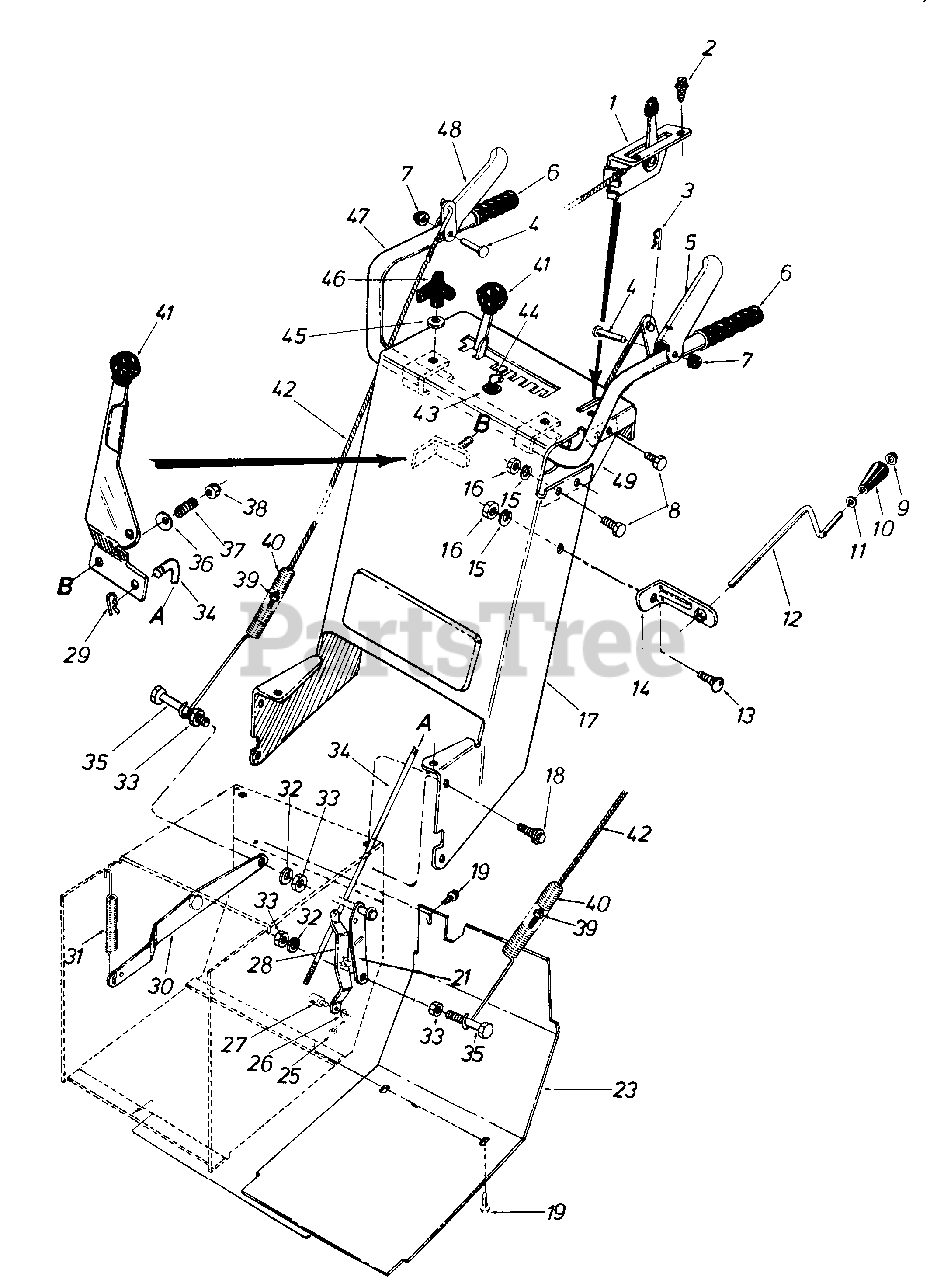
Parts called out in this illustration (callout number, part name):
1	Throttle Control Ass'y. Comp.
2	Hex Wash. Hd. AB-Tap Scr. #8 x .50
3	Hairpin Cotter 3/32" Dia. x 1.00" Lg.
4	Clevis Pin .375" Dia. x 1.88" Lg.
5	Drive Clutch Grip Ass'y. - L.H.
6	Grip Handle
7	Push Cap for 3/8" Rod
8	Hex Bolt 5/16-24 x .62" Lg.
9	Push Nut for 3/8" Rod
10	Knob w/.38" Dia. Hole
11	Fl. Wash. .385" I.D. x .62" O.D. x .063"
12	Chute Crank .38 Dia. x 35" Lg.
13	Carriage Bolt 5/16-18 x .62" Lg.
14	Chute Control Brkt.
15	L-Wash. 5/16"
16	Hex Nut 5/16-24 Thd.
17	Handle Panel Ass'y.
18	Hex Wash. Self-Tap Scr. 5/16-24 x .50" Lg.
19	Hex Wash. Self-Tap Scr. 5/16-24 x .50 Lg.
21	Drive Clutch Brkt. Ass'y.
23	Frame Cover
25	Cotter Pin 3/32" Dia. x .75" Lg.
26	Fl. Wash. .344" I.D. x .62" O.D. x .063
27	Ferrule - Engagement
28	Shifting Linkage Brkt.
29	Hairpin Cotter 3/32" Dia. x 1.00" Lg.
30	Auger Clutch Brkt.
31	Ext. Spring .38" O.D. x 3.18" Lg.
32	L-Wash. 1/4" I.D.
33	Hex Nut 1/4-28 Thd.
34	Shifting Rod
35	Hex Bolt 1/4-28 x 1.75" Lg.
36	Bell-Wash. .400 I.D. x .88 O.D. x .060
37	Comp. Spring .39 I.D. x .88
38	Hex Ins. L-Nut 3/8-24 Thd.
39	Hex Ins. L-Nut 1/4-20 Thd.
40	Spring .75" O.D. x 5.0" Lg.
41	Shift Handle Ass'y.
42	Lock-Out Cable 30.5" Lg.
43	Ignition Switch
44	Ignition Key
45	Bell-Wash. .345 I.D. x .88 O.D. x .060
46	Three Arm Knob - 5/16-18 Thd.
47	Handle Ass'y.
48	Auger Clutch Grip Ass'y. - R.H.
49	Handle Support Brkt.
